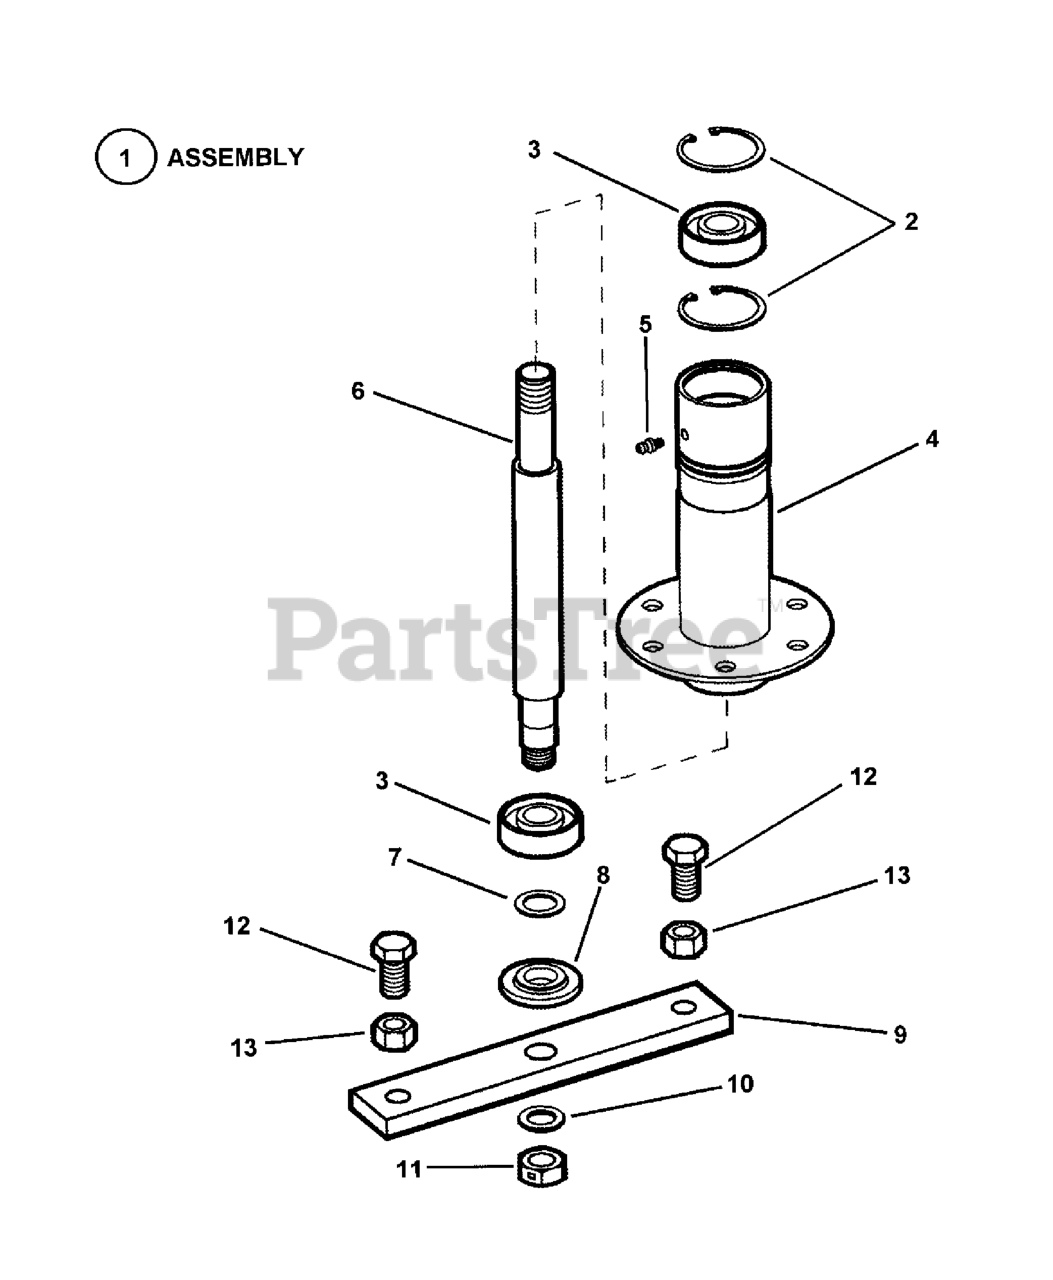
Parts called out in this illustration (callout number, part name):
1	ASSEMBLY, Spindle
2	RING, 1.85" Internal Retaining
3	BEARING, Spindle
4	ASSEMBLY, Spindle Housing
5	LUBE FITTING, 3/16" Press-In
6	SPINDLE, Rider (10.327" overall length)
7	WASHER, .77 x 1.13 x .06 Flat
8	WASHER, Spindle
9	HOLDER, Blade
10	SPACER, Blade Centering
11	NUT, 5/8-18 Hex Center Lock Jam
12	SCREW, 1/2-20 x 1-1/4" Hex Head Cap, GR 5
13	NUT, 1/2-20 Hex, GR 5 or B
